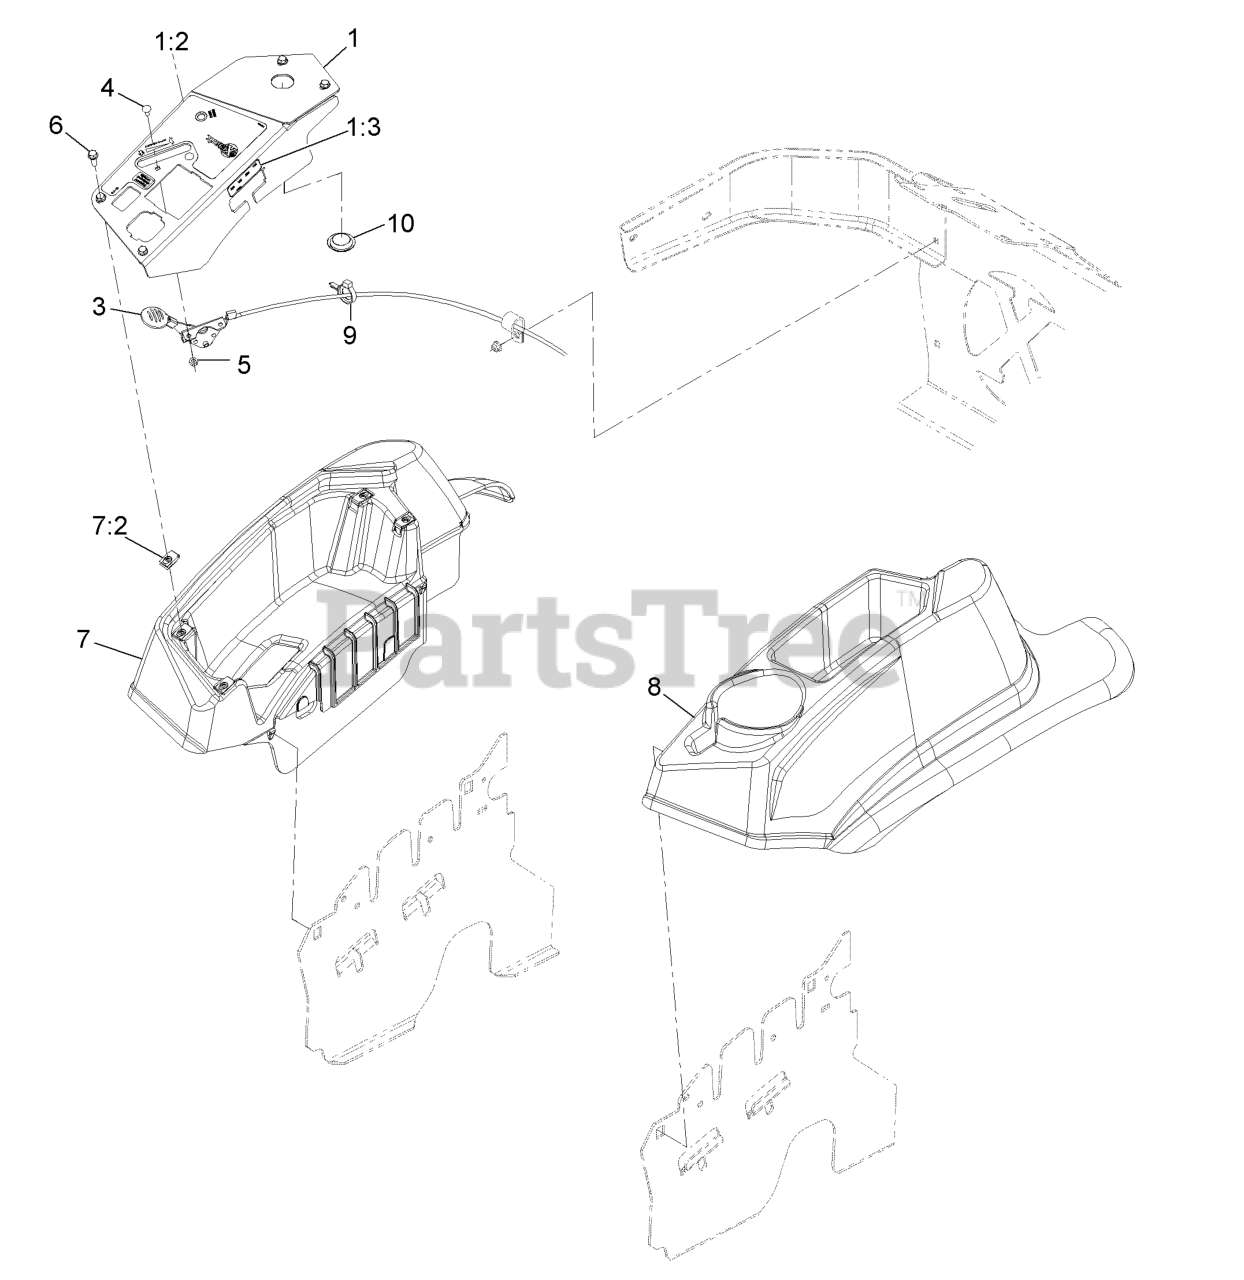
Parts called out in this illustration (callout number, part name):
1	ASM,CONTROL PANEL W/DECAL
1:2	DECAL,CONTROL PANEL EFI
1:3	DECAL-FUSE
3	ASM,THROTTLE CABLE
4	BOLT-CARR
5	NUT-LOCK, NI
6	SCREW-HWH
7	CONSOLE,RH AS ASM
7:2	Nut-Retainer-Panel 1/4-20
8	CONSOLE, LH AS
9	CLAMP-HOSE
10	PLUG-PLASTIC
